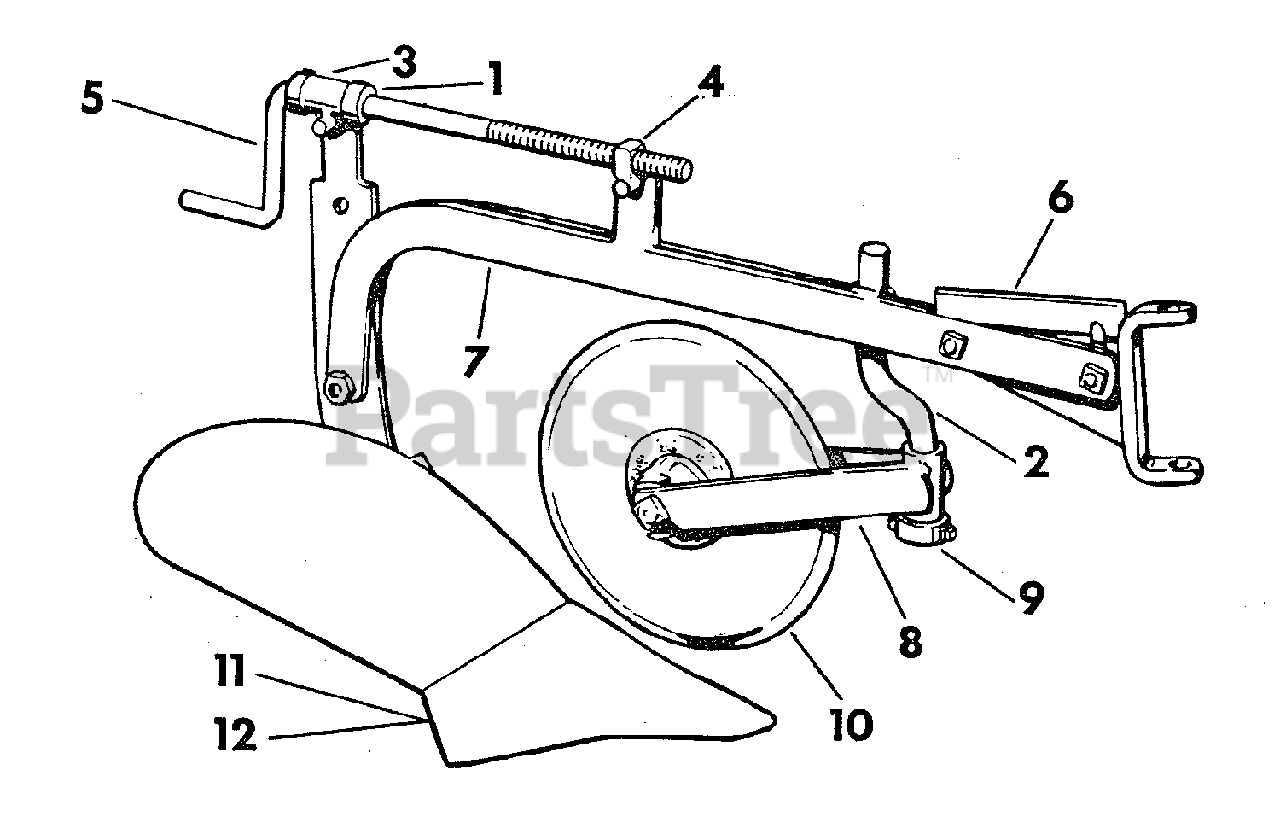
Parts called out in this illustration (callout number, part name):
1	COLLAR, Set
2	STANDARD, Coulter
3	BEARING ASSEMBLY, Depth Screw
4	NUT ASSEMBLY, Adjusting, Depth Screw
5	SCREW, Depth
6	END ASSEMBLY, Beam
7	BEAM ASSEMBLY, Plow
8	FORK ASSEMBLY, Coulter
9	COLLAR, Coulter Stop
10	COULTER, 10", Complete w/Bearings & Bolt
